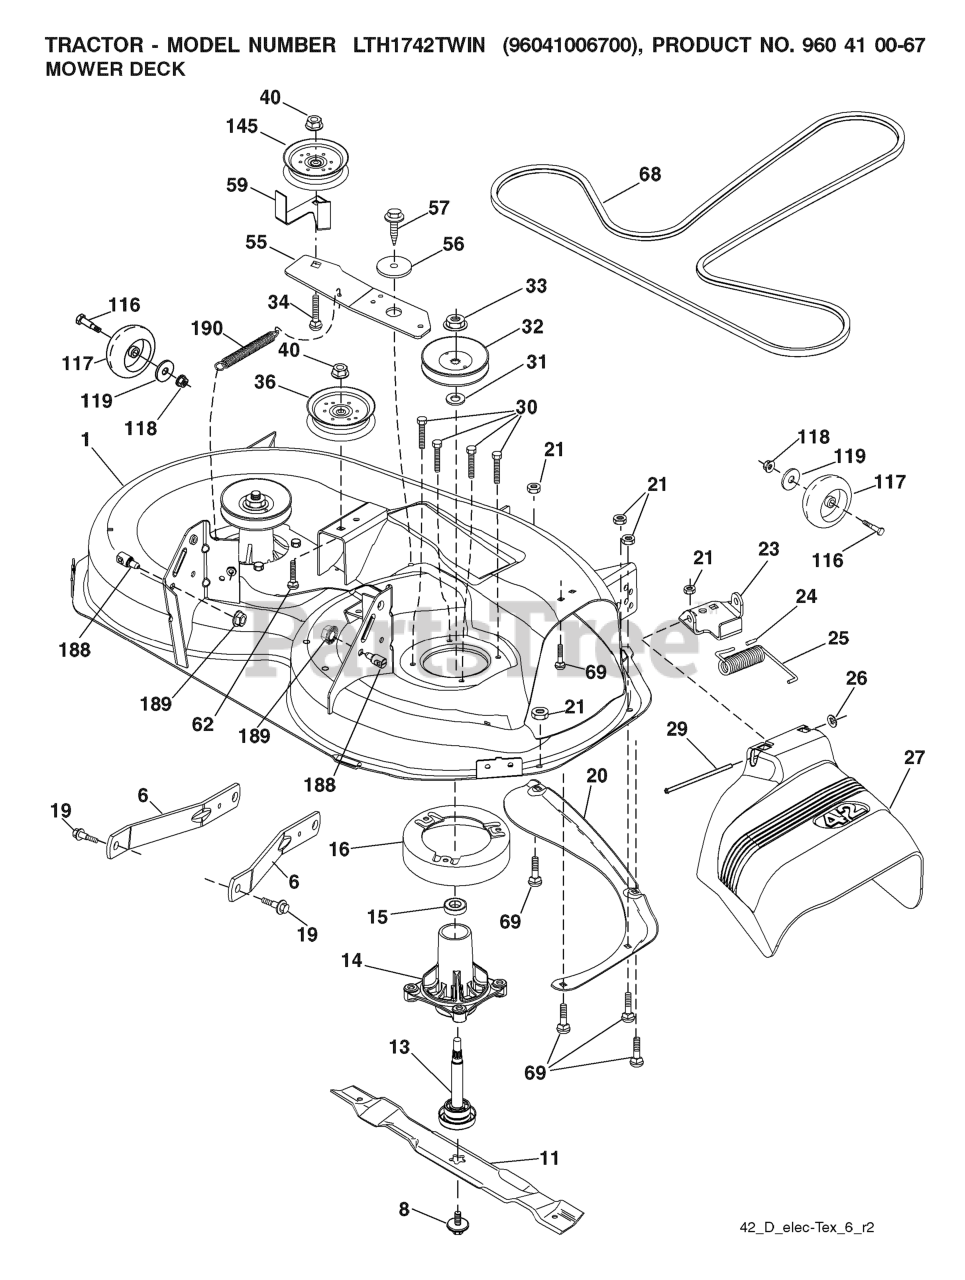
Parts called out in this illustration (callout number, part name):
1	DECK.WELDMENT.42"
6	ARM.SUSPENSION.MOWER.R
8	BOLT.WASHER.ASM.7/16-2
11	42" HI-LIFT BLADE
13	SHAFT.ASM.MDRL.N/GREASE.38
14	RP.HOUSING.MANDREL.4PT.
16	STRIPPER.MANDREL.ROUND.BLACK
19	BOLT.SHOULDER
20	BAFFLE.VORTEX
21	LOCKNUT
23	BRKT.DEFLECTOR.38"2005+
24	CAP-SLEEVE LT
25	SPRING.TORSION.DEFLECT
26	NUT PUSH M
27	SHIELD.DEFLECTOR.MOWER.42"BLAC
29	ROD.HINGE
30	SCREW, WASHER HEAD
31	WASHER.SPACER.MANDREL
32	PULLEY/MANDREL
33	NUT.FLANGE.LOCK.TOP
34	BOLT.3/8-16X1.50
36	PULLEY.IDLER.2006
40	NUT LOCK FLG 3/8-16 UNC
56	SPACER.RETAINER
57	SCREW 3/8-16X1
59	GUARD, BELT
68	BELT V SECONDARY
69	BOLT
116	BOLT.SHLD."A"2.41."B"1.66
117	WHEEL.GAGE.HALF.SPOKED
118	NUT LOCK FLG 3/8-16 UNC
119	WASHER.5/16.FLAT.STE.STD.
145	PULLEY.IDLER.48"PRIMARY
188	STUD.FASTNER.W/ANTI-ROTATE
189	NUT LOCK HEX FLANGE 5/16-18
190	SPRING.MOWER.DRIVE.ELECTRIC
